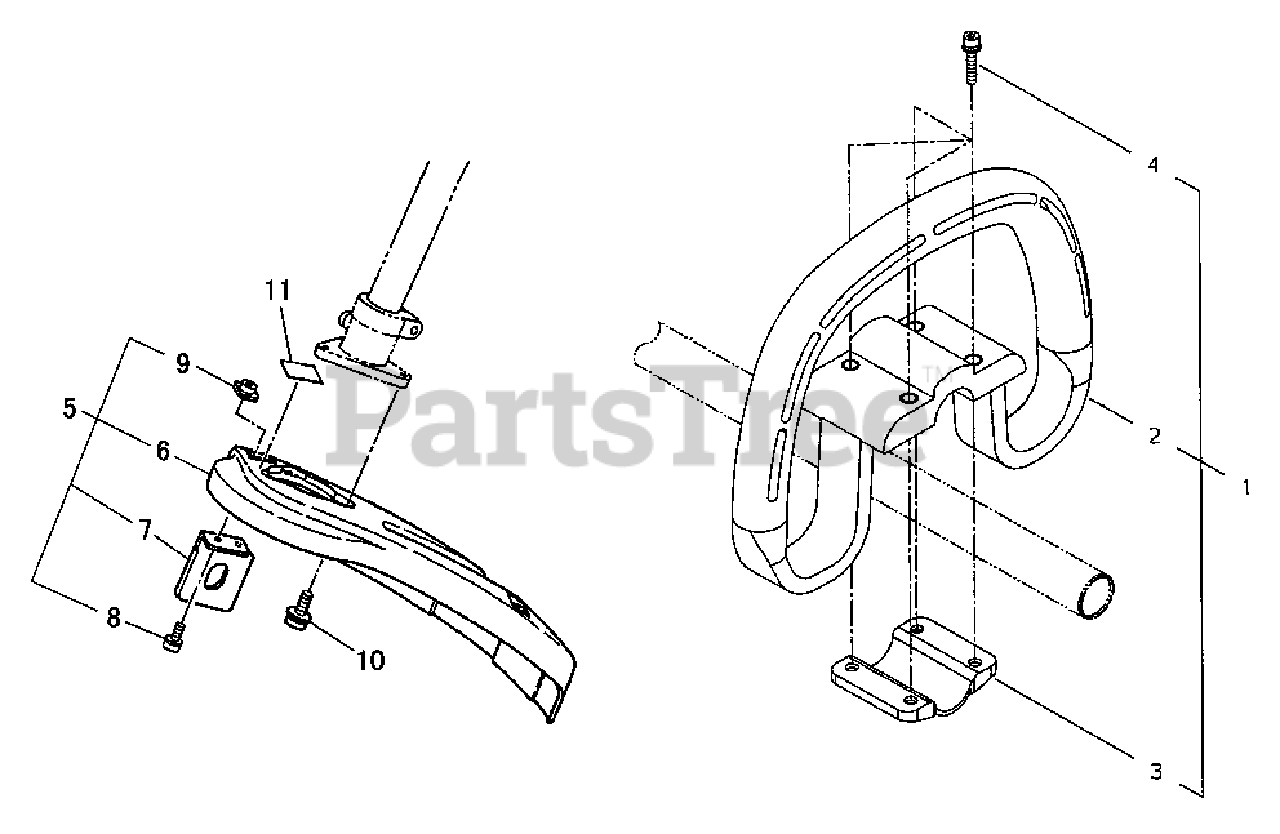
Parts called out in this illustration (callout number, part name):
1	HANDLE ASSY
2	HANDLE
3	CLAMP - LOWER
4	SCREW - 5X25
5	SHIELD ASSY
6	SHIELD
7	KNIFE, TRIMMER LINE
8	SCREW - 4X16
9	NUT
10	SCREW - 5X16
11	LABEL - CAUTION
